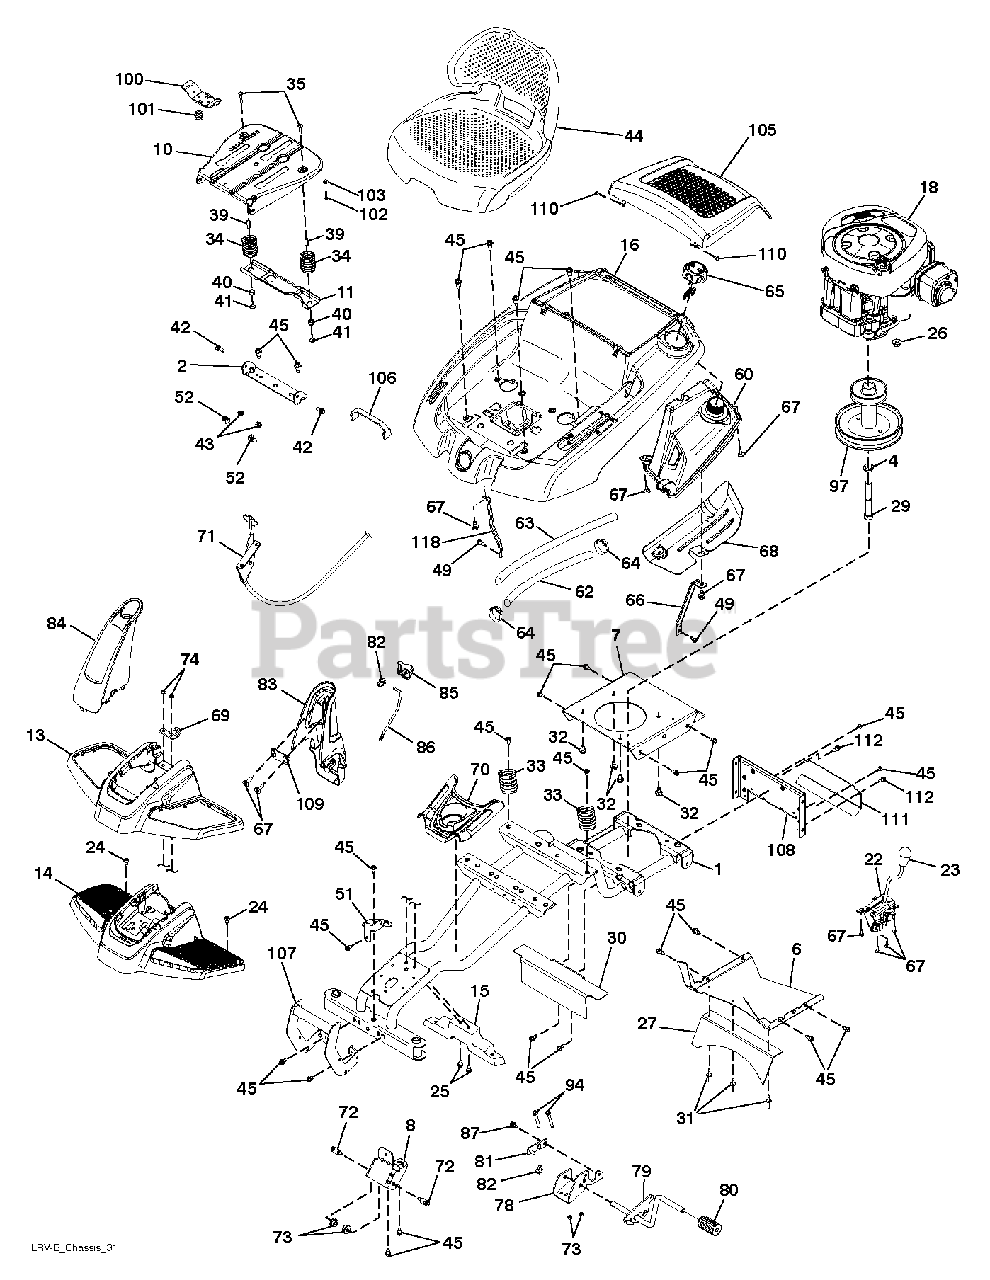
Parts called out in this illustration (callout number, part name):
2	BRKT.PIVOT.FENDER
4	LOCKWASHER
6	PAN.PNT.BELLY.LRVB.GUARD
8	BRACKET.SUSP.CHAS.FR.LRV
10	PAN.ASM.SEAT.SHORT.SLD.ADJ.TEX
11	BRKT.MNT.OPC.SW.SEAT.
13	COVER.AESTH.FOOTREST.MS428
14	FOOTREST.STRUCTURAL.
15	SUPPORT. FOOTREST.LRV.MS428
22	CABLE.BLADE.ENGAGE.LRVB.2014
23	KNOB.OVAL.CUSTOM.BLACK
24	SCREW.#10 X 0.750.BOS (2 2)
25	BOLT.CARRIAGE
26	NUT
27	GUARD PAN EXTENSION PLASTIC
29	Hex Bolt, 7/16-20 X 3.0 Gr5
30	ENGINE.PLATE.EXTENSION.LRVB
32	SCREW.3/8-16
33	SPRING COMPRESSION
34	SPRING COMPRESSED
35	BOLT.ROUND.HEAD.SQUARE.NECK
39	SPACER SPLIT 28X.96
41	NUT T
42	BOLT.SHOULDER.5/16-18
43	NUT.71038.31-18.HEX.NYLOCK
44	COMFORT.SEAT.ASSEMBLY
45	SCREW
49	SCREW 5/16-18X1
51	BRACKET, STEERING SUPPORT
52	PUSH CLIP
60	LRVB.FUEL.TANK.ASSEMBLY.EPA
63	RP PURGE LINE
64	HOSE CLAMP
65	CAP.FUEL.2 WAY VENT
67	SCREW.#10 X 0.500
70	CONSOLE.CENTER.CUPHOLDER
72	STUD.FASTNER.W/ANTI-ROTATE
73	NUT LOCK HEX FLANGE 5/16-18
74	NUT T
80	COVER.PEDAL.BRAKE.LRV
82	RETAINER CLIP
87	BOLT.SHOULDER.5/16-18X
94	BOLT HEX FLGHD 5/16-18X3 GR. 5
97	PULLEY.ENGINE.LRVB.PMST
100	HANDLE.SLIDE.SEAT.TEX.BLACK
101	SPRING.LATCH.SEAT.TEX
103	WASHER 13/32 X 2-3/8 X 12GA
105	Engine Cover, Lrvb Pattern 2.X428
106	STRAP.BATTERY.LRVB
107	WELDMENT.FRT.PNT.BRUSHGAD.LR
112	SCREW
